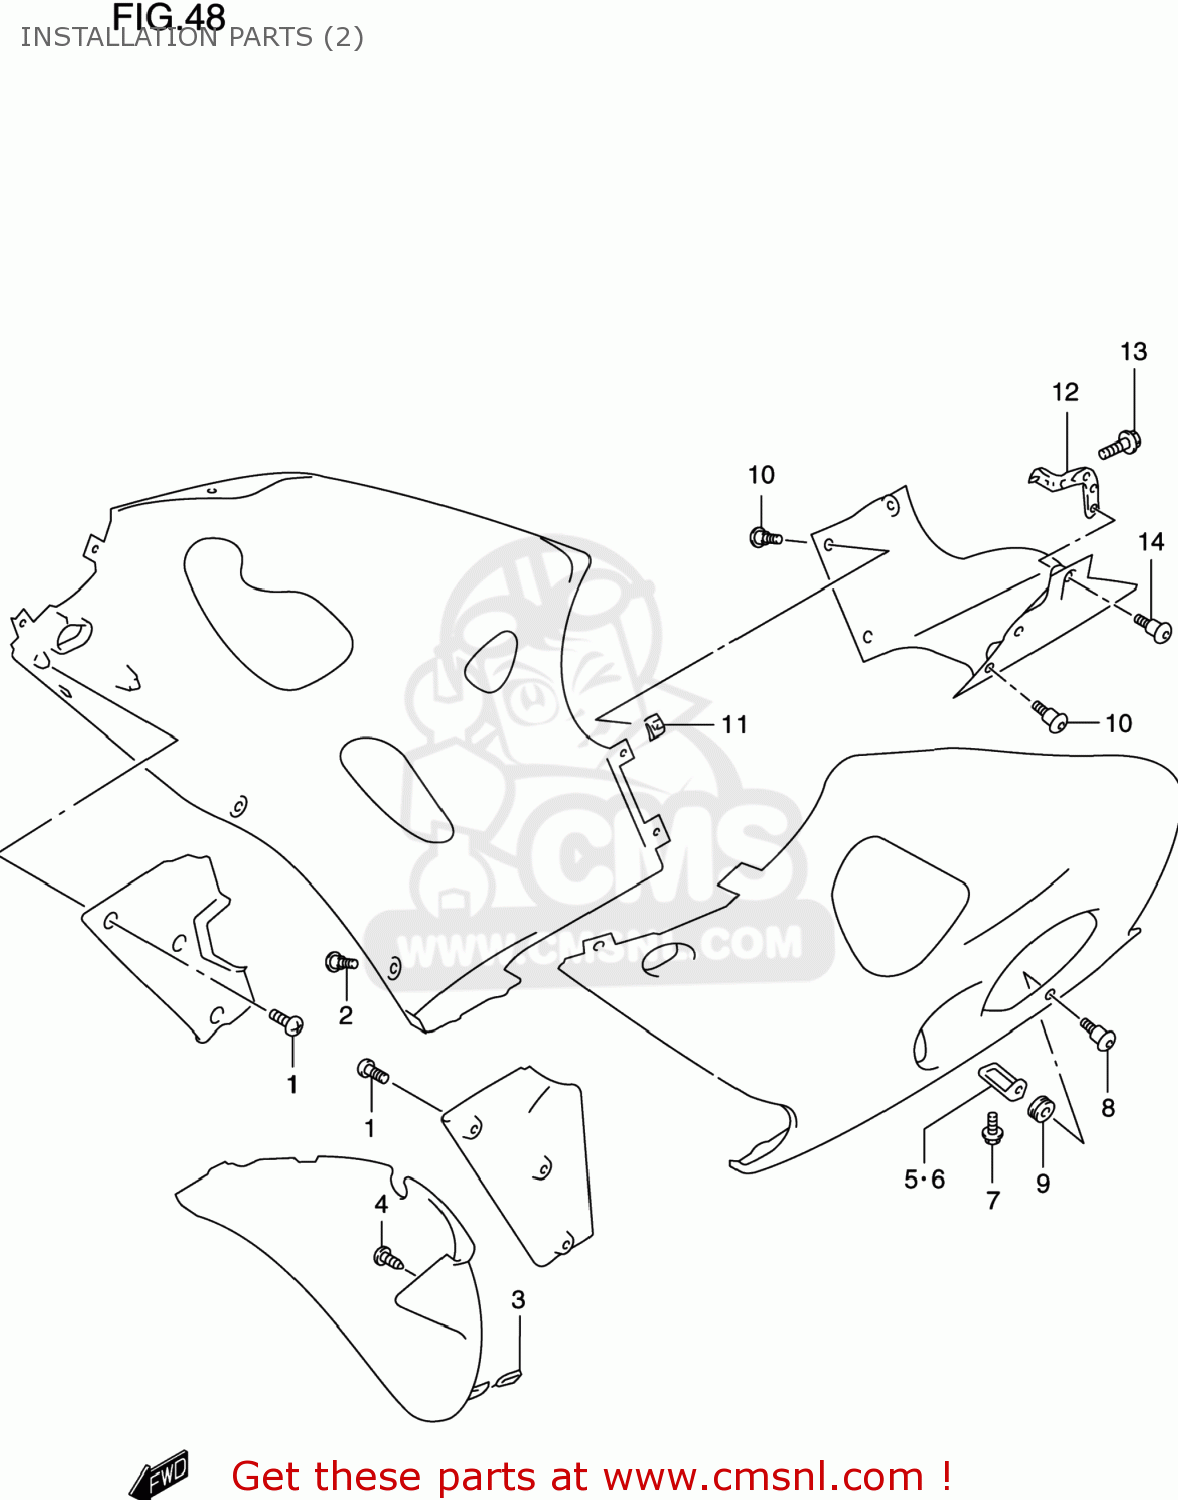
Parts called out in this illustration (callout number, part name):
1	SCREW
2	SCREW(5X16)
3	NUT,COWL
4	SCREW
5	BRACKET,UNDER COWLING,LOWER
6	BRACKET,UNDER COWLING,LOWER
7	BOLT
8	SCREW(6X20)
9	CUSHION
10	SCREW(5X16)
11	NUT,COWL
12	BRACKET,RR UNDER COWLING
13	BOLT
14	SCREW(5X16)
